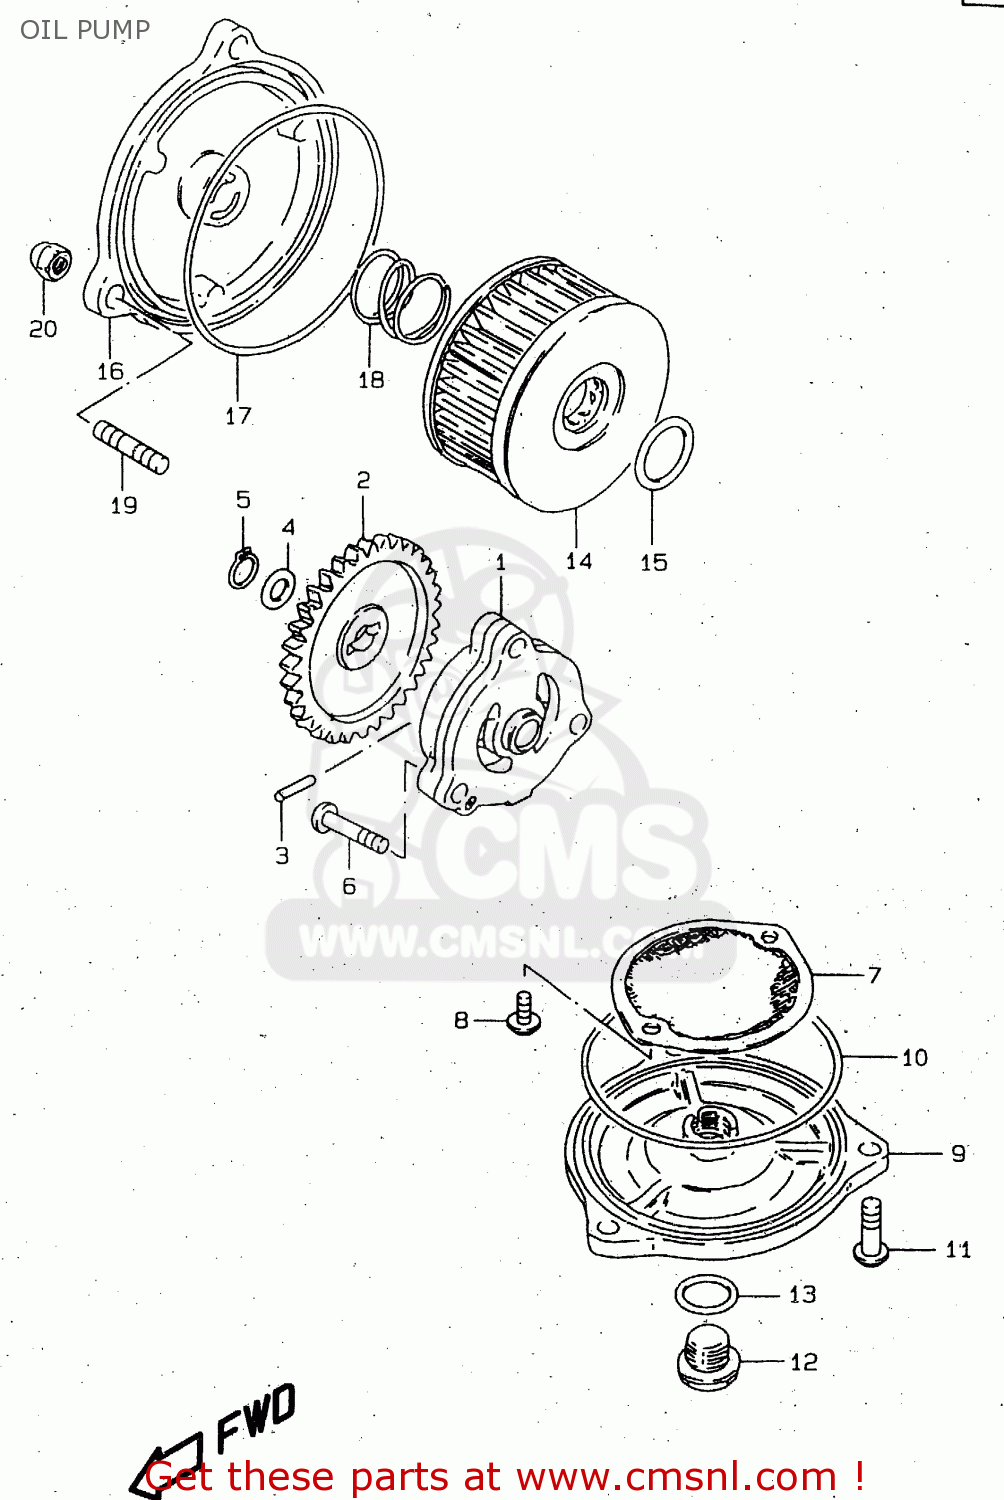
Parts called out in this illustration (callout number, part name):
1	PUMP, ENGINE OIL
2	GEAR,OIL PUMP DRIVEN(NT:33)
3	PIN(4X15.8)
4	SHIM
5	CIRCLIP,10MM
6	SCREW
7	STRAINER,ENGINE OIL
8	SCREW
9	CAP,OIL STRAINER
10	O RING(D:2.4,ID:85)
11	SCREW
12	PLUG
13	GASKET(13.8X18.8X4.8) (NAS)
14	FILTER ASSY,ENGINE OIL
15	O RING(D:2.4,ID:15.8)
16	CAP,OIL FILTER
17	O RING(D:2.4,ID:73)
18	SPRING
19	STUD 6X12
20	NUT
